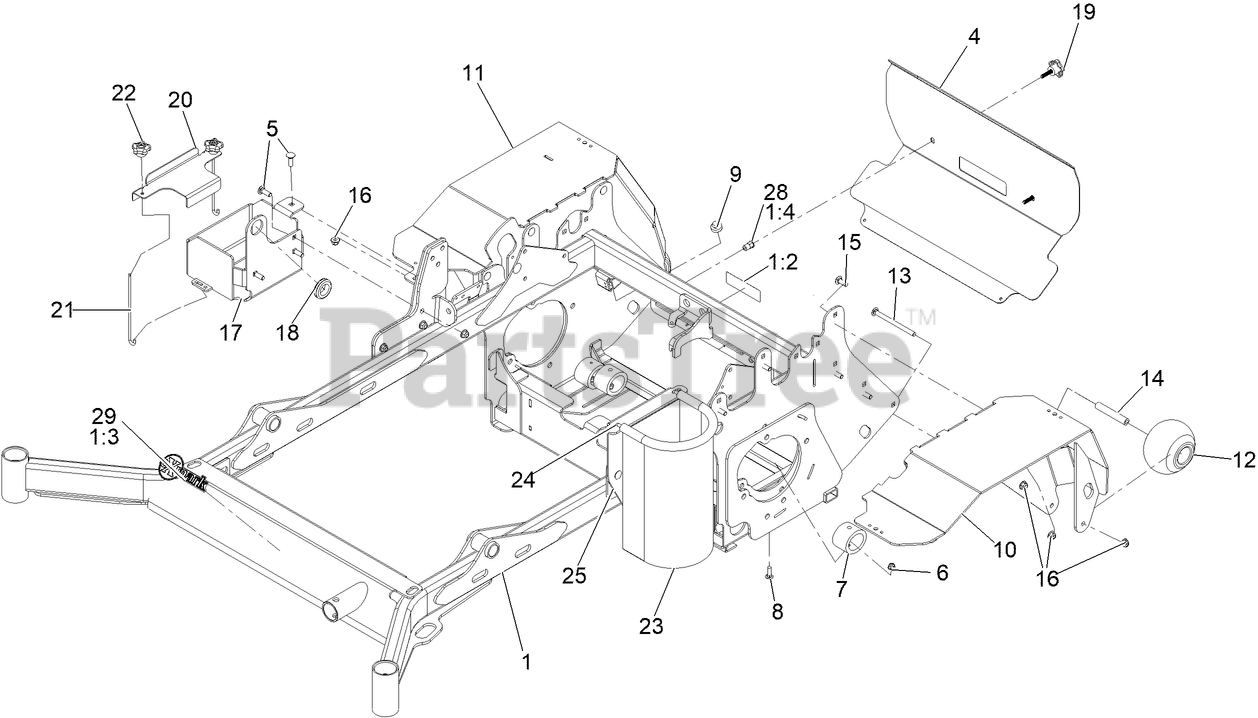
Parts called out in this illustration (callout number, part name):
1	ASM-Frame Stand On 72
1:2	DECAL-COVER, MISSING
1:3	DECAL-EXMARK LOGO
1:4	NUT-CLINCH
4	GUARD-REAR FOOT
5	Bolt-Carriage 3/8-16 X 1 1/4
6	NUT-HF, NI
7	BUMPER-ISOLATOR
8	BOLT-CARR
9	BUMPER-RUBBER
10	FENDER-LH WELDT
11	FENDER-RH WELDT
12	ROLLER-SCALP, ANTI
13	BOLT-CARR
14	SPACER- ROLLER
15	SCREW-CARR
16	NUT-HF, NI
17	BATTERY TRAY
18	GROMMET
20	BRACKET-BATTERY HOLD DOWN
21	BOLT-HOLDDOWN
22	KNOB-HANDLE
23	BAG-TRASH
24	ROD-BAG, TRASH
25	BRACKET-TRASH BAG MOUNT
28	NUT-CLINCH
29	DECAL-EXMARK LOGO
